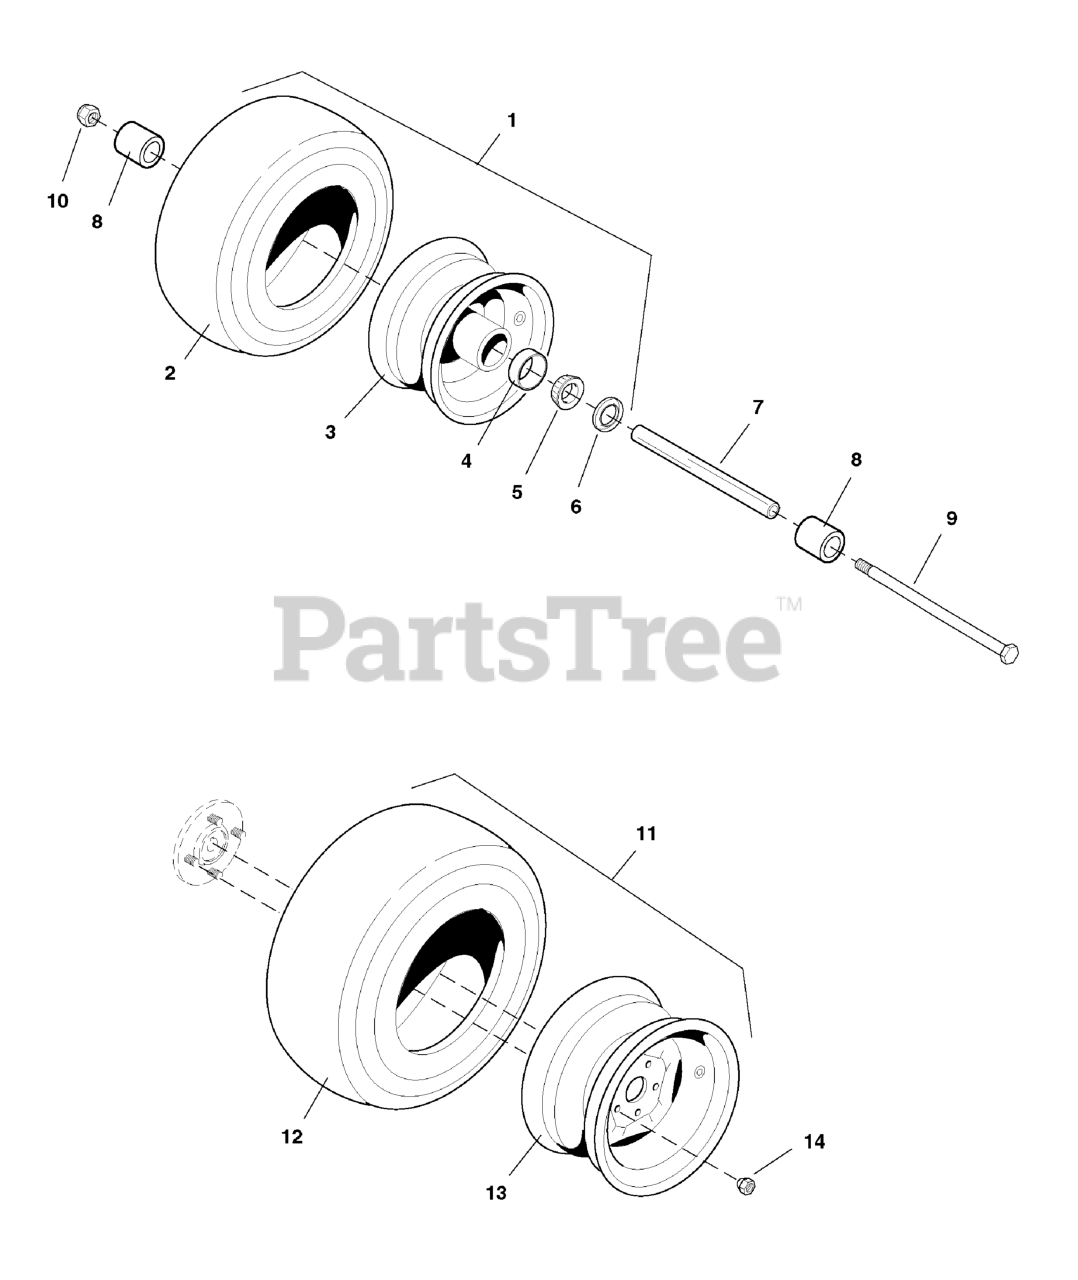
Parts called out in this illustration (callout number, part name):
1	WHEEL & TIRE ASSEMBLY, 18 x 7.5 x 8, Silver, Complete
2	TIRE, Rear, 18 x 7.5 x 8
3	WHEEL ASSEMBLY, 8 x 3.75, Silver, Complete
4	BEARING CUP
5	BEARING, Tapered Roller
6	GREASE SEAL
7	STEERING TIRE AXLE
8	SPACER, 1.01 X 1.25 X 2.06
9	BOLT, 5/8-11 x 9-1/2
10	NUT, 5/8-11 Hex Side Lock
11	WHEEL & TIRE ASSEMBLY, 20 x 10 x 8, Complete
12	TIRE, 20 x 10 x 8
13	WHEEL ASSEMBLY, 8 x 7
14	LUG NUT, 1/2-20
